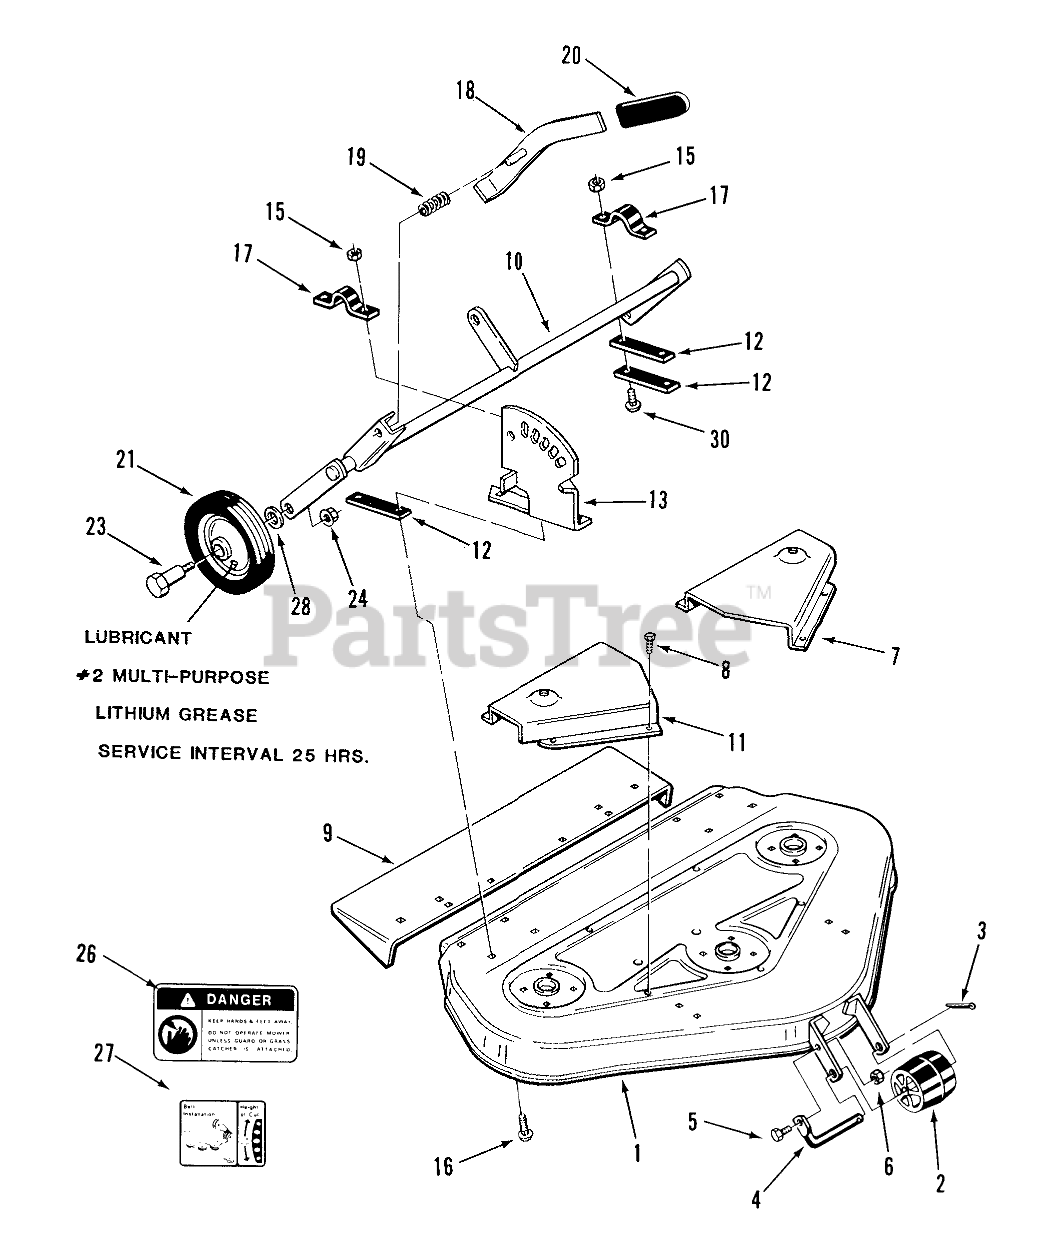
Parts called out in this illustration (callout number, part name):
1	Mower Deck
2	Roller
3	Cotter Pin
4	ROLLER-SHAFT
5	H H C S
6	Nut
7	Cover-Belt
8	SCREW -4
9	Chute Extension
10	Gage Wheel Support
11	Belt Cover RH
12	Bar
13	Quadrant
15	Nut
16	Bolt
18	Lever
19	SPRING-COMPRESSION
21	WHEEL
23	BOLT-SHOULDER
24	Nut
26	Danger Decal
27	DECAL-HEIGHT & BELT
28	WASHER
30	Bolt
